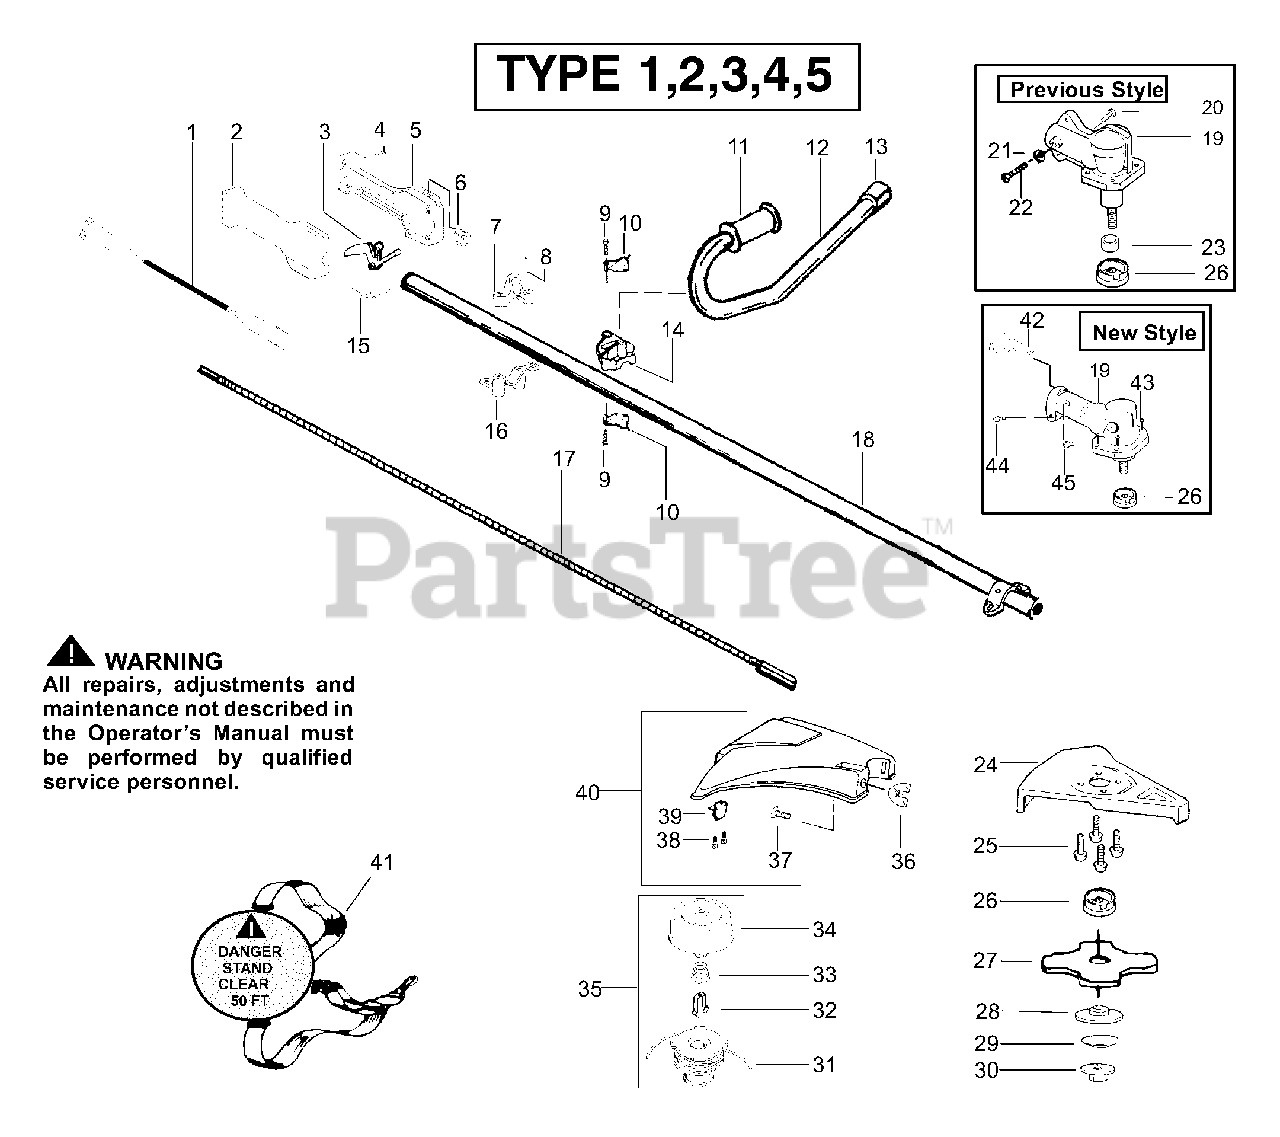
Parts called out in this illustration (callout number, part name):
1	Assy-Wire (type 2,3,4,5)
2	Hsg.-Throttle Right Type 1
2	Hsg.-Throttle Right Type 2,3,4,5
3	Lever-Throttle Type 1
3	Lever-Throttle Type 2,3,4,5
4	Screw Type 1
4	Screw Type 2,3,4,5
5	Hsg.-Throttle Left Type 1
5	Hsg.-Throttle Left Type 2,3,4,5
6	Kit-On/Off Switch
7	Assy-Clamp Upper
10	Bracket-Handlebar
11	Grip-Handlebar Fin
12	Handlebar w/decal
13	End Cap-Handlebar
14	Clamp-Handlebar
15	Spring-lever return (Type 2,3,4,5)
16	Assy-Clamp Lower
17	Shaft-Flex
18	Kit-Drive Shaft Assy
19	Kit-Gear Box Ass'y.
20	Screw-Pinch Clamp
23	Sleeve-Seal
24	Kit-Metal Shield
26	Dust Cup
27	Accy-4 Point Blade
28	Washer-blade ret.
29	Washer-Belleville
30	Nut-Flange LH
31	Accy-Spool w/Line
32	Retainer-Spool
33	Spring-Return
34	Assy-Hub
35	Accy-Cutting Head
36	Wingnut
38	Screw
39	Line Limiter
40	Kit-Shield Ass'y.
41	Assy-Shoulder Strap
42	Bracket-Shield
45	Screw-Align
